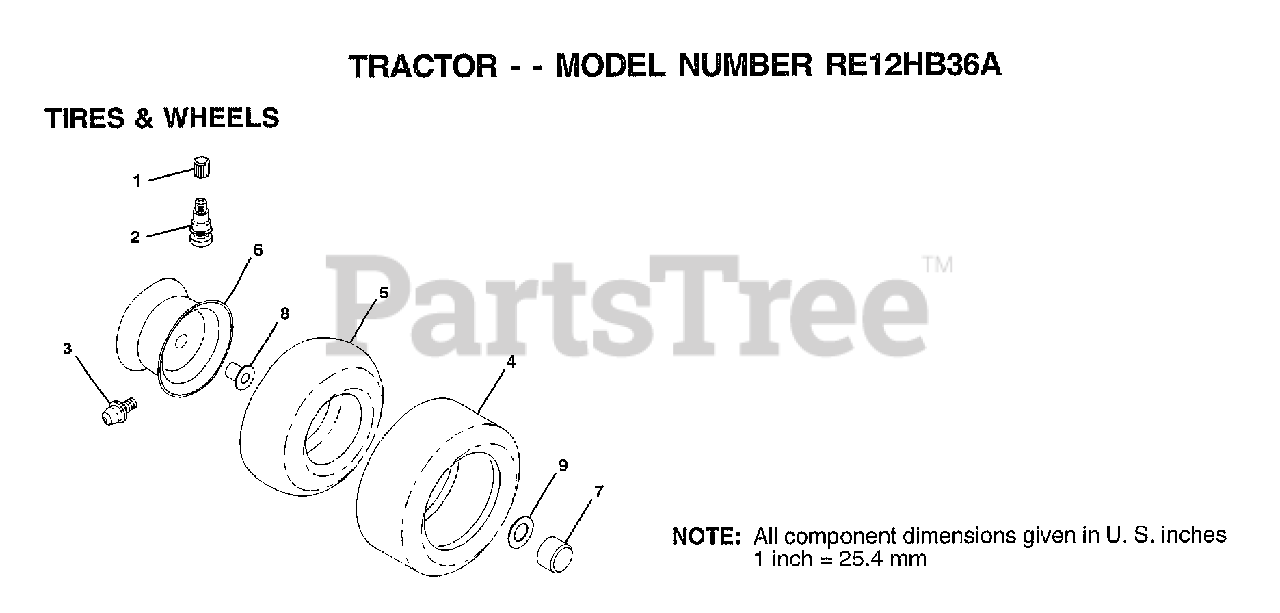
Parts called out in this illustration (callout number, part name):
1	VALVE CAP
2	VALVE STEM LT
3	FITTING LT
5	TUBE.5.3/4.5/6
5	TUBE.16X6.5/7.5-8
6	"RIM FRONT 6"""
6	"RIM ASM REAR 8"""
7	HUB CAP
8	"FLANGE, BEARING"
9	WASHER
